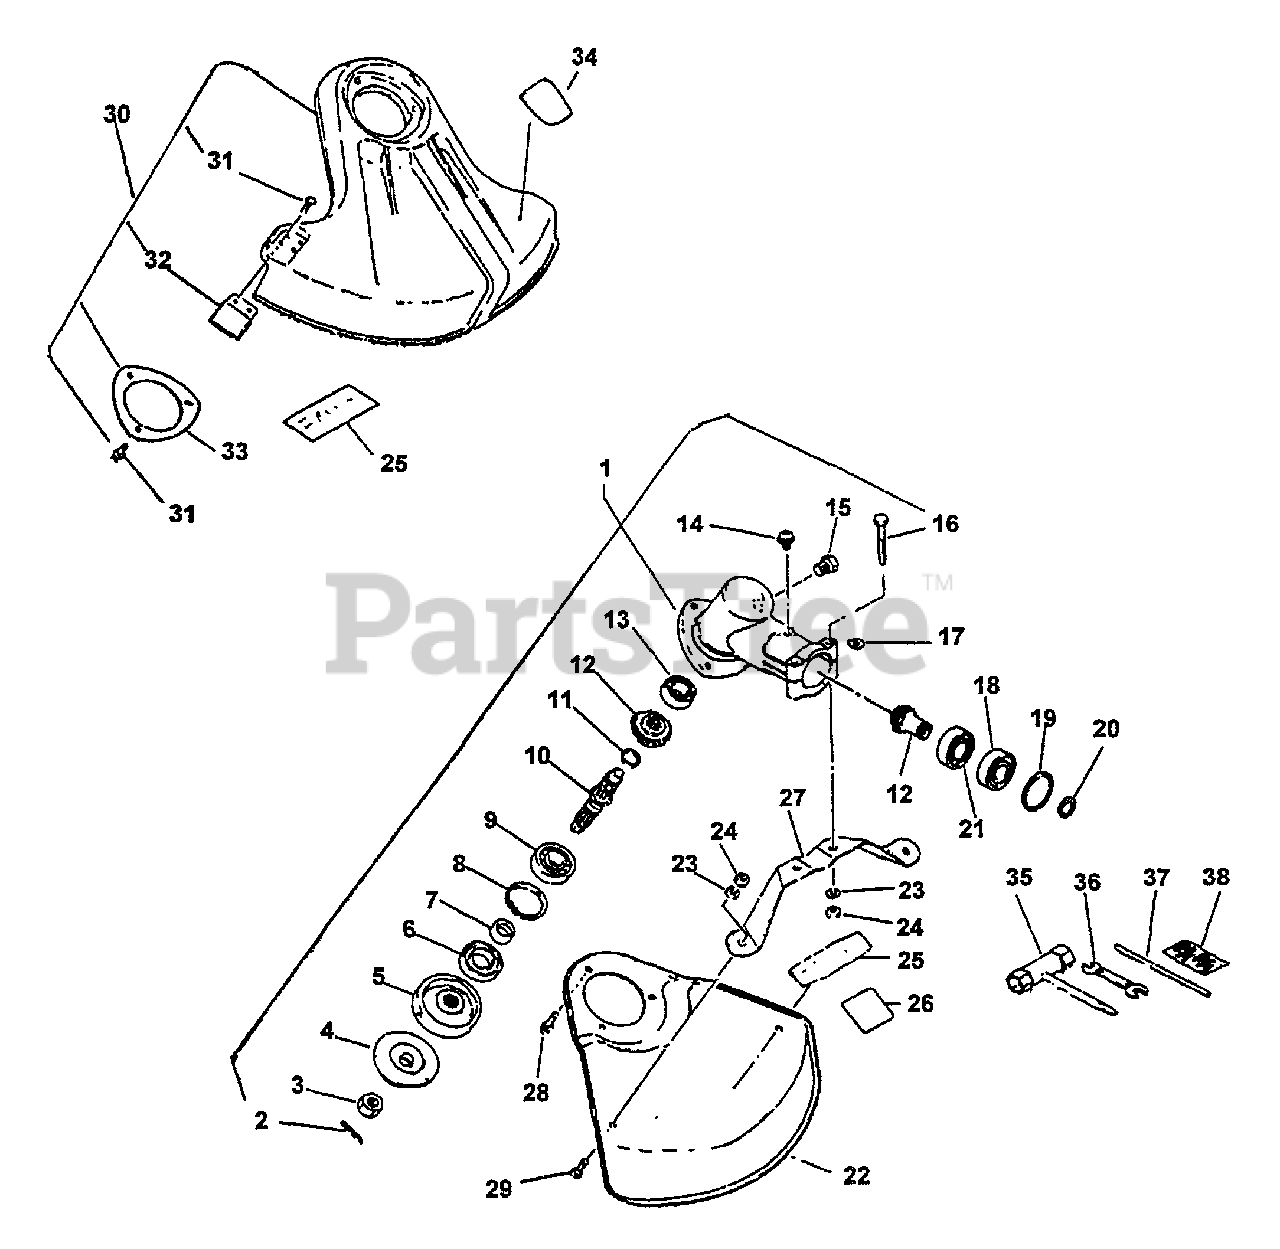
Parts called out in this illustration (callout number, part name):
1	GEAR CASE ASSY
2	PIN, COTTER 2×22
4	PLATE, ADAPTOR - LOWER
5	PLATE, ADAPTER - UPPER
6	SEAL, OIL 22
7	SPACER 11.8×15×9
8	RING, SNAP Ø32
9	BEARING, BALL - 6201 C3
10	SHAFT, GEAR
11	RING, SNAP Ø10
12	GEAR SET
13	BEARING, BALL 609
14	SCREW 5×10
15	BOLT - 5×8
16	BOLT 5×35 SP
18	BEARING, BALL 6900Z
19	RING, SNAP Ø22
20	RING, SNAP Ø12
21	BEARING, BALL 6900
22	SHIELD ASSY
23	WASHER, SPRING 5
24	NUT M5
25	LABEL, ECHO
26	LABEL - CAUTION
27	BRACKET, SHIELD MOUNTING
28	SCREW 5×10
29	SCREW 5×8
30	DEBRIS SHIELD ASSY
31	SCREW 5×16
32	CUTTER, LINE
33	PLATE, SHIELD Ø49.5 MM
34	LABEL, CAUTION
35	T-WRENCH 17x-19 L200
36	SPANNER 8×10
37	TOOL, LOCKING 5×120 MM
38	PIN, COTTER 2×22 (PKG. OF 10)
